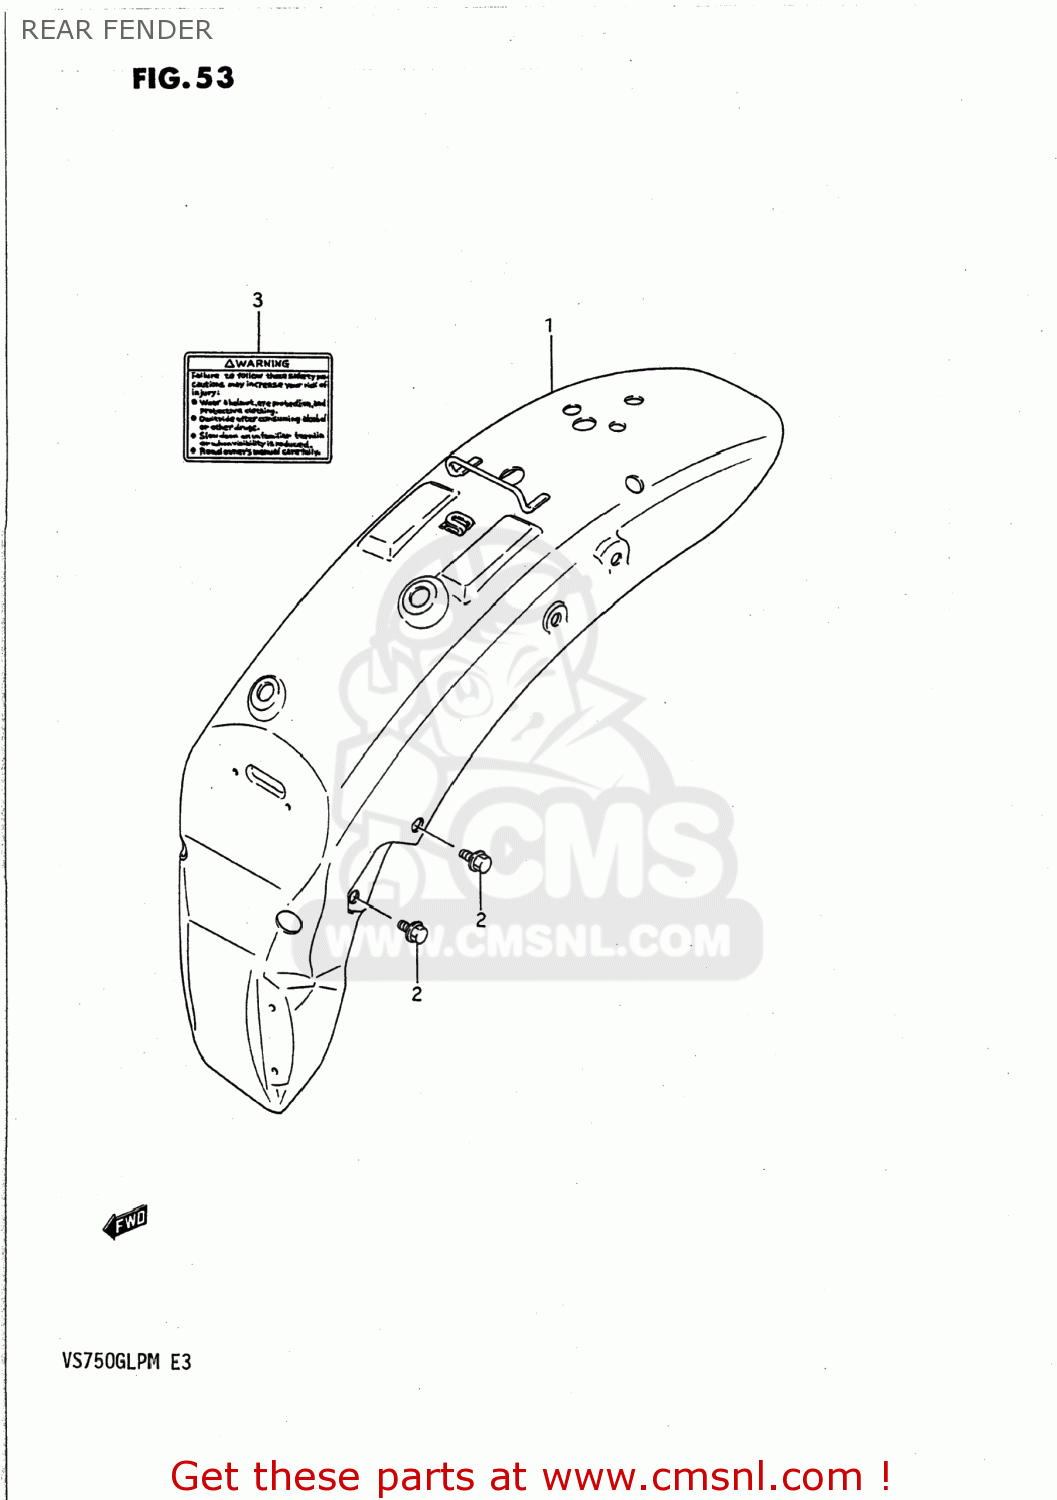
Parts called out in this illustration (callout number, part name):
1	FENDER COMP,REAR
2	BOLT
3	LABEL
